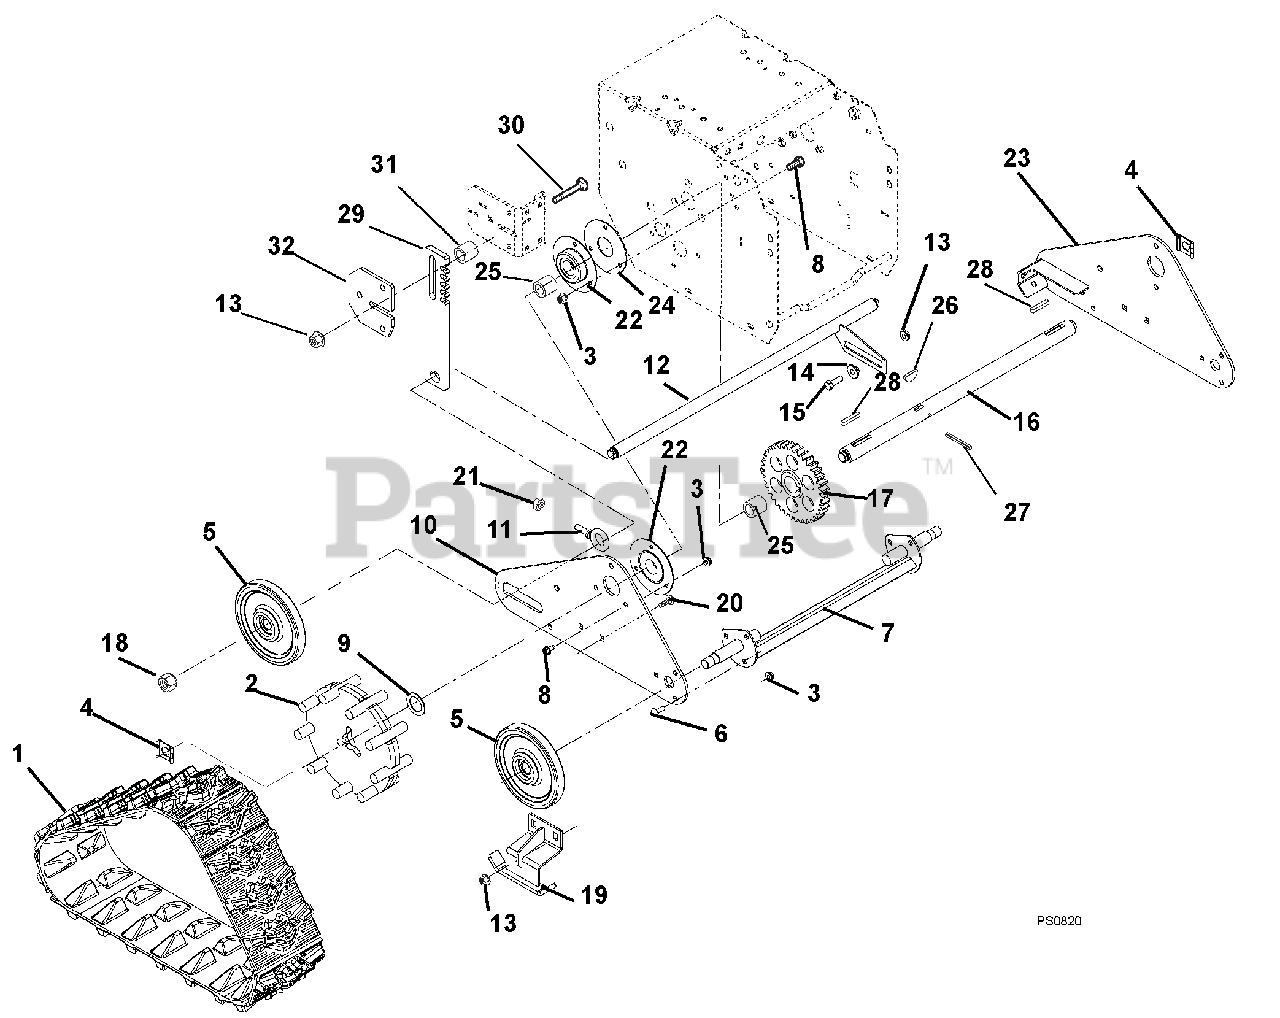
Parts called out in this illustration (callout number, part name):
1	TRACK, RUBBER
2	WHEEL, DRIVE-TRACK
3	@NUT-LK-TOP-FLG .25-20 YWZC
4	CLIP, SNAP .625 DIA
5	WHEEL, BOGIE - SINGLE BEARING
6	@BLT-RDHDSQNK .25-20X.75 G5YZ
7	AXLE, FRONT-DELUXE TRACK
8	@BLT-HEX .25-20X.75 GR5 YWZC
9	WSHR-FL-STL 1.010X1.505X.062YZ
10	SIDE PLATE, RH-DELUXE TRACK
11	BLT-EYE .375-16X.880 YWZC
12	AXLE, REAR - DELUXE TRACK
13	@NUT-LK-TOP-FLG .31-18 YWZC
14	BSHG, FLG .325X.499X.26X.88
15	@BLT-HEX .31-18X1.00 GR5 YWZC
16	AXLE, TRACK-DELUXE
17	GEAR, SPUR
18	@NUT-LK-NYL .625-18 YWZC
19	RUNNER, GUIDE-TRACK
20	@BLT-RDHDSQNK .31-18X.75 G5YZ
21	@NUT-LK-TOP-FLG .38-16 YWZC
22	BRG-FLG 1.003/1.000 3 BOLT
23	SIDE PLATE, LH-DELUXE TRACK
24	PLATE, BEARING SPACER
25	BSHG-SLV, 1.012X1.125X1.00
26	KEY-WDRF .25X.750X.313 SAE91
27	PIN-ROLL .188X1.25
28	KEY-RECT .25X.188X1.00
29	STOP, HEIGHT ADJUSTER - DELUXE
30	@BLT-RHDSHSQNK.31-18X1.25 G5YZ
31	SPACER .50 X .32 X .42
32	PLATE, HEIGHT ADJUSTER
